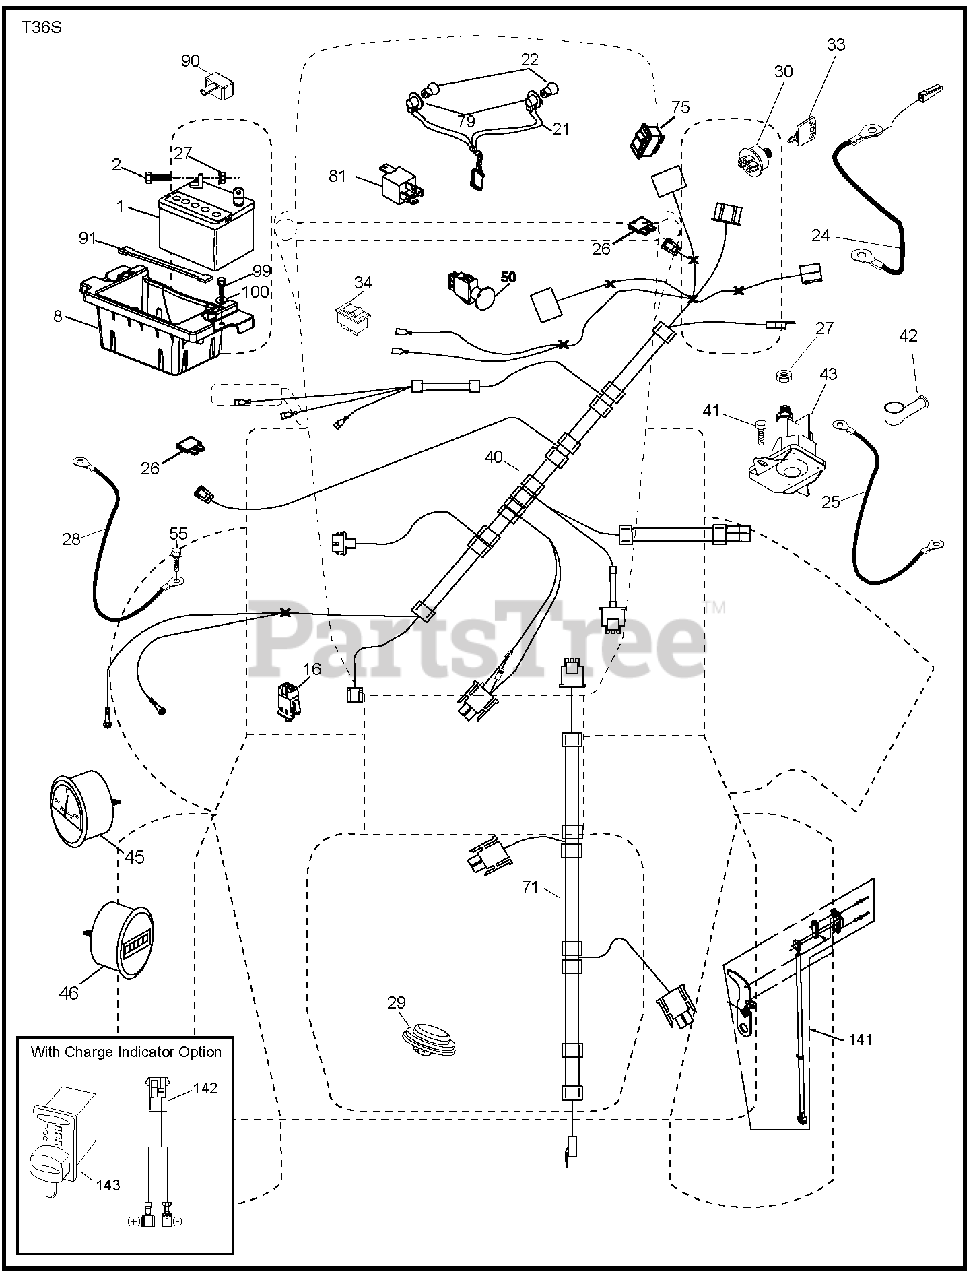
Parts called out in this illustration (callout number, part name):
1	REPL BY 532 12 38-99
2	BOLT.HEX.1/4.X.3/4.DICHROMATE
8	BOX.BATTERY.MOUNT.FRONT.LT
16	SWITCH INTERLOOK PUSH-IN
21	HARNESS.W/LIGHT SOCKET
22	LIGHTBULB
24	CABLE.BATT.POS.WIRE.TG.DA SOL
25	CABLE.STARTER.6G.BL/RED.17.5
26	FUSE 20AMP
27	NUT
28	CABLE GROUND 6 GA 21" 90T BLK
29	SWITCH.SEAT.DELTA.OPC.
30	SWITCH.IGN.DELTA.W.LGH.ROS
33	KEY.CHAIN.BLISTER.PACK.GEN.USA
34	SWITCH LT
40	HARNESS.DASH.ELECTRIC.LIFT
41	SCREW
42	TERMINAL COVER
43	SOLENOID.W/BRASS.PLUNGER
45	AMMETER.ROUND.SNAPIN
46	HOURMETER.ROUND.SNAPIN
50	PTO SWITCH
55	SCREW 5/16"
71	HARNESS
75	SWITCH.ROCKER.DECKLIFT
79	BULB HOLDER ASM.
81	RELAY HARNESS.SEALED
90	COVER.TERMINAL.BATTERY
91	STRAP.BATTERY.MOUNT.FRONT
99	SCREW HEXWSHR 1/4-20X3/4
141	KIT.G700/G730.ROS 71750
